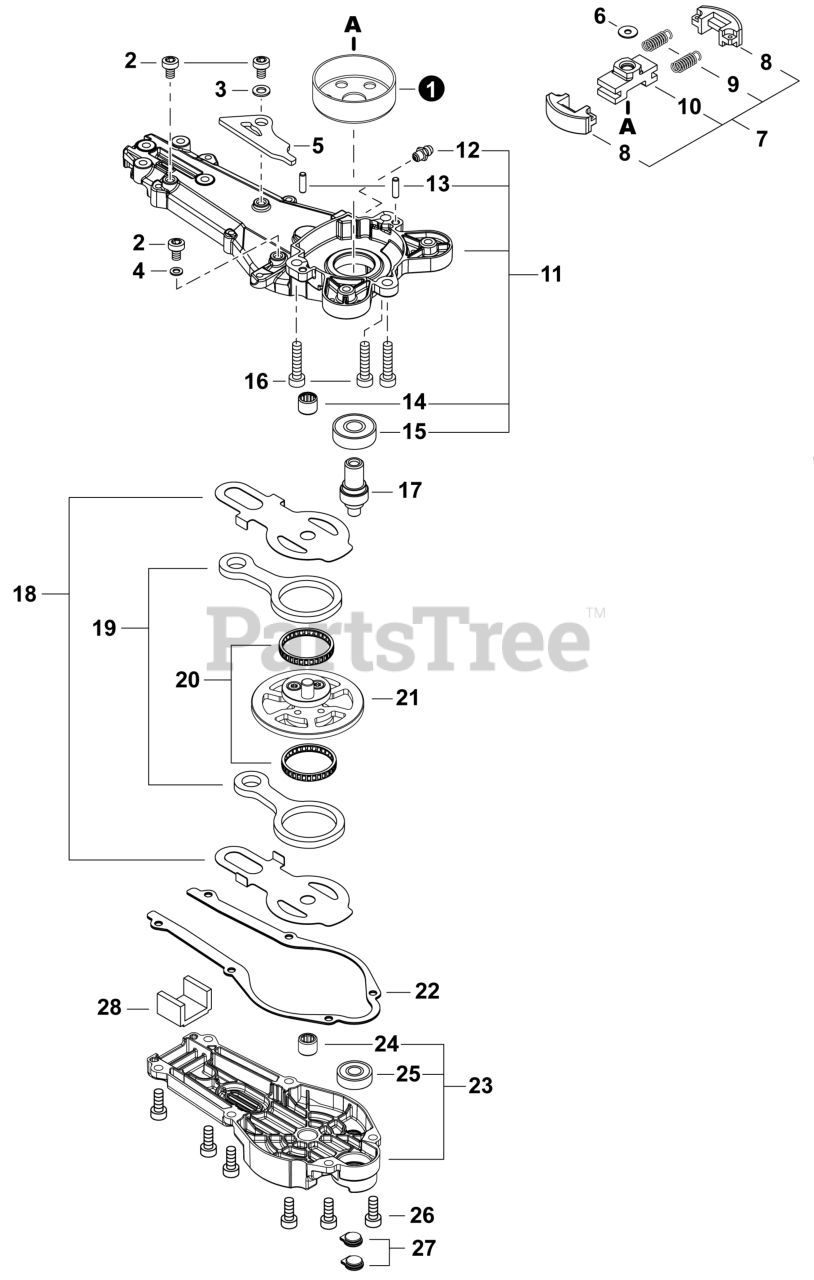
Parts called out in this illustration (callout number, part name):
1	DRUM, CLUTCH
2	BOLT, TORX 5x6
3	WASHER 5
4	WASHER 5.5x12x0.8
5	CUSHION
6	WASHER 8
7	CLUTCH ASSY
8	SHOE, CLUTCH
9	SPRING, CLUTCH
10	HUB, CLUTCH
11	HOUSING ASSY, GEAR CASE
12	FITTING, GREASE
13	PIN, LOCATING 4x10
14	BEARING, NEEDLE 8
15	BEARING, BALL
16	BOLT, TORX 6x20
17	SHAFT, PINION
18	PLATE, SIDE
20	BEARING, NEEDLE 30
21	GEAR, SPUR
22	GASKET, GEAR CASE
23	COVER ASSY, GEAR CASE
24	BEARING, NEEDLE 8
25	BEARING, BALL 608ZZ
26	BOLT, TORX 5x16
28	PACKING, FELT
